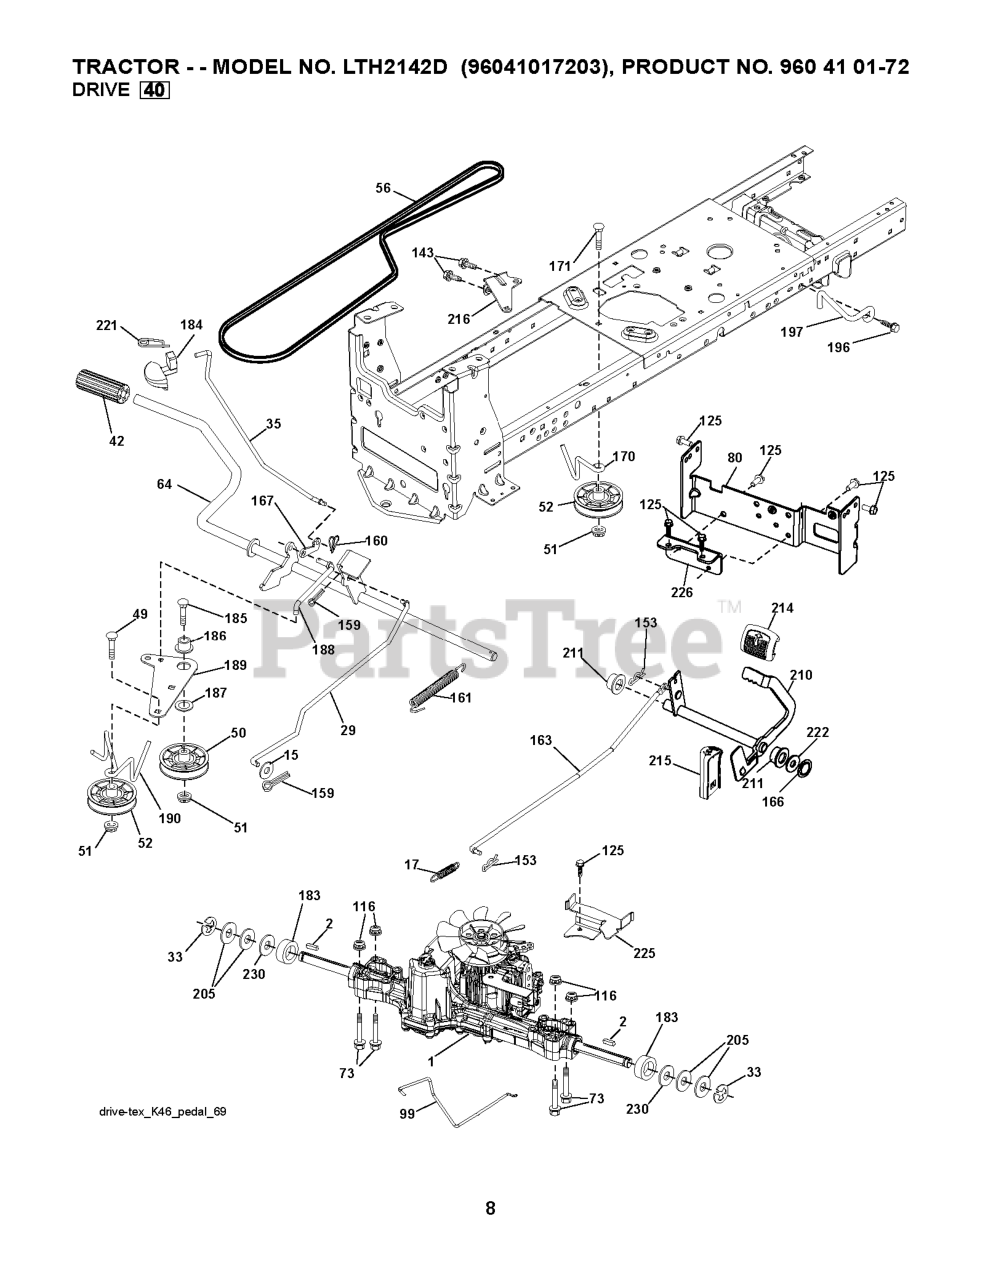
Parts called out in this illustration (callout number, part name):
2	SQUARE KEY
15	WASHER
17	SPRING.BRAKE.K46.GREEN
29	ROD.BRAKE.K46
35	ROD.CNTRL.PARK.PREDATOR.LT.TEX
42	PEDAL COVER T
50	IDLER.FLAT.910.OFFSET
51	NUT LOCK FLG 3/8-16 UNC
52	IDLER.V-GROOVE.910.OFFSET
56	V-BELT.MOWER.92.40.42/K46
64	SHAFT.ASM.PEDAL.BRK.CNTR
73	BOLT HEX 5/16-18 GR 5
80	STRAP TORQUE
99	ROD.SPRING.BYPASS.K46.LT.Z
116	NUT LOCK HEX FLANGE 5/16-18
125	SCREW
143	Screw 5/16-18 x 1/2 Hex, Self Tapping 5/16-18 x 1/2
153	RETAINER M
159	COTTER PIN
160	RETAINER CLIP
161	SPRING, RETURN LT
163	ROD.CONTROL.PEDAL.K46
166	NUT.PUSH.625
167	LATCH.BRAKE.SPRING
170	KEEPER.V-IDLER.CENTER.
171	BOLT
183	SPACER AXLE
184	HANDLE PARKING BRAKE
186	SPACER.RETAINER
187	WASHER 12/32X2X10GA
188	RP.LINK.CLUTCH.GROUND.DRIVE
189	BELLCRANK.GROUND.DRIVE.TEX.
190	KEEPER.BELLCRANK.DRIVE
196	SCREW 3/8-16X1
197	LINK.CLUTCH.ANIT-ROTAT
210	ROCKER.ASM.PEDAL.CONTR
211	BEARING.NYLON
214	PEDAL.FORWARD.PAD.TEX
215	PEDAL.REVERSE.TEX.GT.4
216	BRACKET.PULLEY.IDLER.W/TEX
221	RETAINER.SPRING.CLIP.H
222	WASHER 21/32 X 1-1/4 X 10 GA.
225	KEEPER.BELT.TRANSAXLE.K46
226	BRACKET.MOUNT.TORQUE.K46.TLT
230	WASHER.HARDENED
